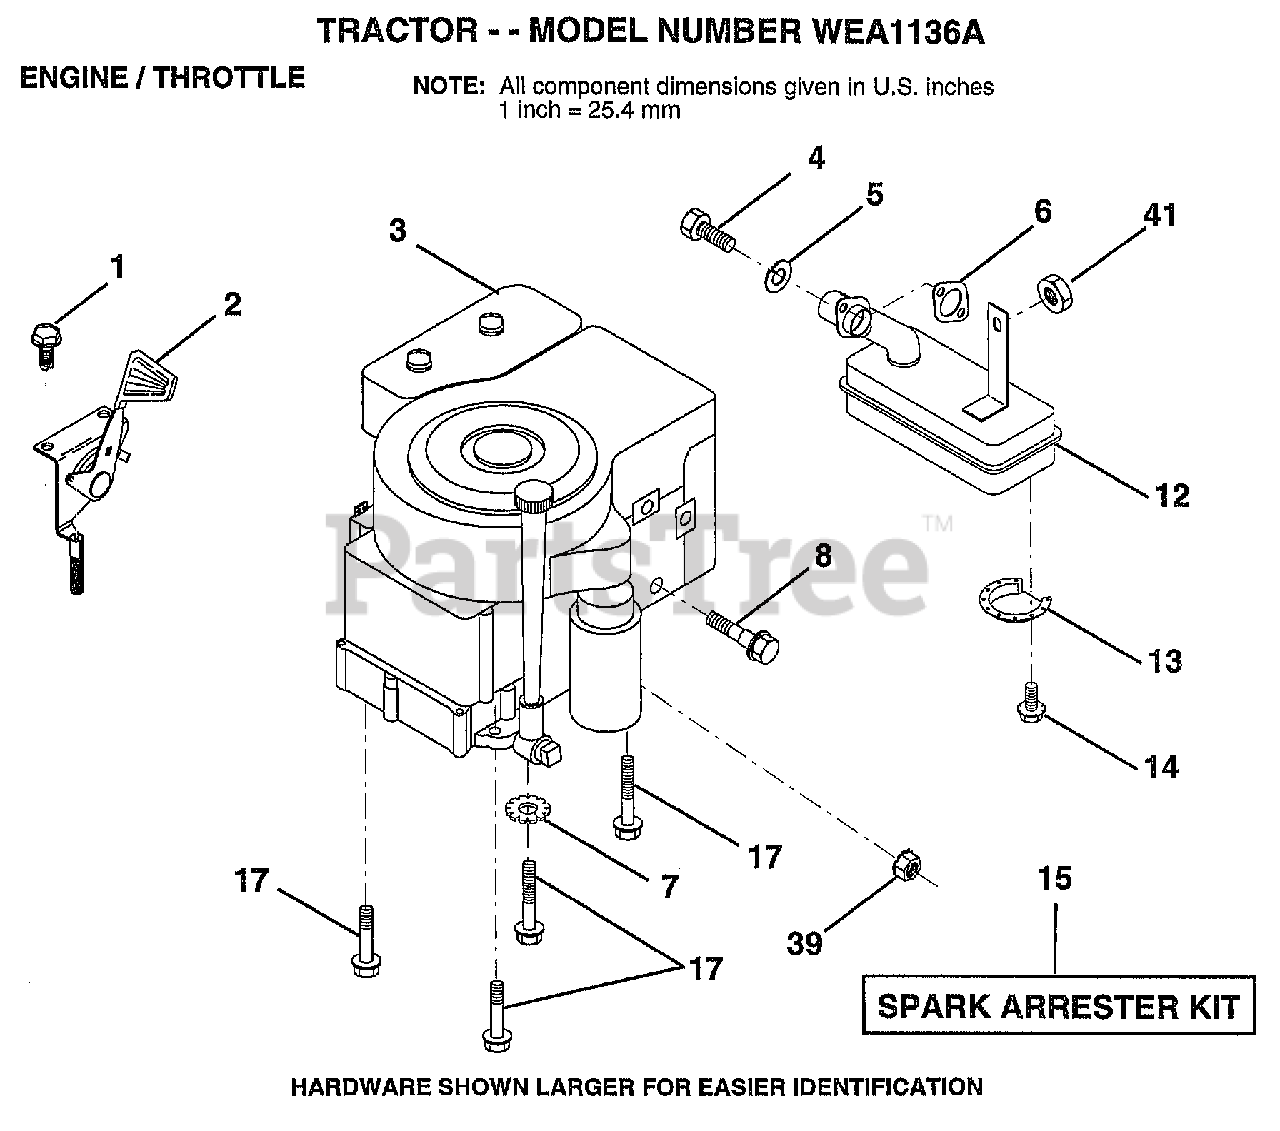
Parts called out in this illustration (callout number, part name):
1	SCREW.1/4-20X1/2
2	"CONTROL,THROTTLE"
4	SCREW HEX HD CAP
5	LOCKWASHER
7	LOCKWASHER
8	SHOULDER BOLT ST
12	MUFFLER-TECH 13HP
13	DEFLECTOR.222573
17	SCREW LT
39	NUT
41	"NUT HEX,LOCK,FLAN"
